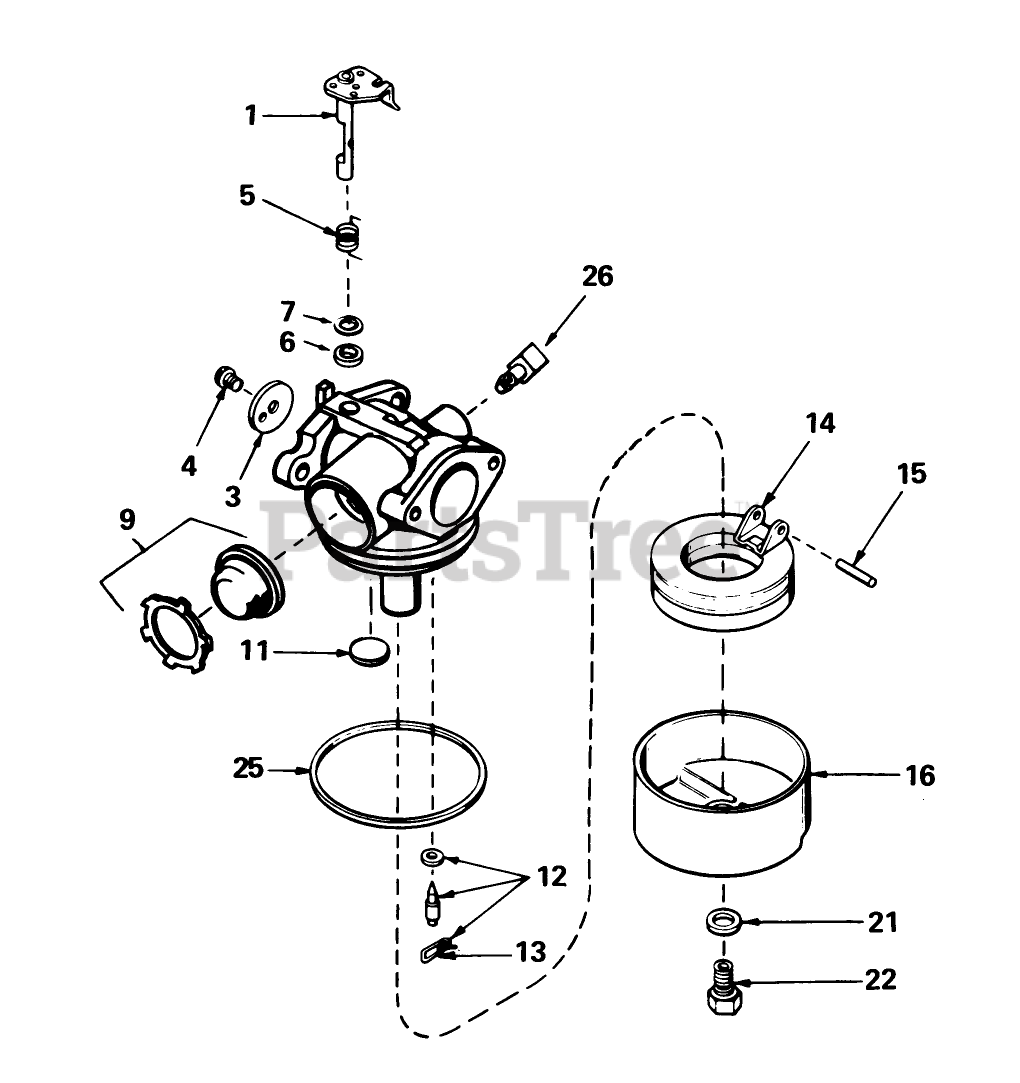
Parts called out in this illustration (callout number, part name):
1	Throttle Shaft and Lever ASM
1	Pin, Spring (Incl. Ref. #7)
2	Washer
3	Throttle-Shutter
3	Retainer
4	Screw-Shutter
4	Washer
5	Spring-Return, Throttle
5	Brake Spring
6	Seal-Dust
6	Dog-Starter
7	Washer-Seal, Dust
7	Spring-Dog
8	Pulley
9	Primer Assy.
9	Rewind Spring
10	Cover-Spring
11	Plug-Welch, Atmospheric Vent
11	Housing-Starter
12	Inlet Needle, Seat Clip Assy. (Incl. No. 13)
12	Rope-Starter (98 cut to length)
13	Clip-Spring
13	Handle-Starter
14	Float
15	Shaft-Float
16	Bowl Float
21	Gasket-Bowl
22	Nut-Bowl
25	O Ring-Bowl, Float
26	Fitting-Fuel
